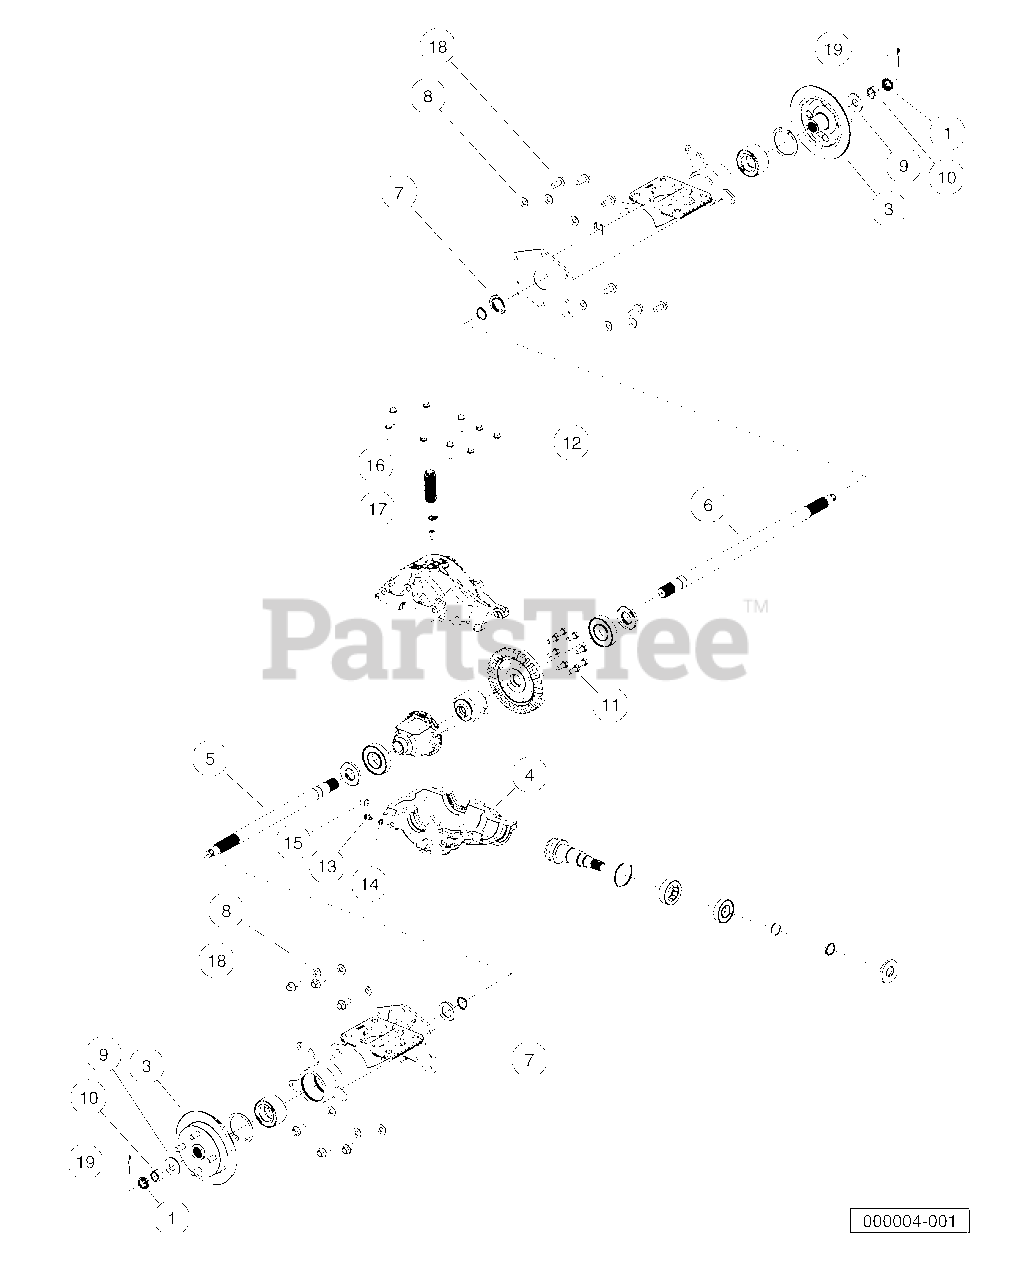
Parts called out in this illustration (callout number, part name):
1	Axle, Rear, Guard Mounts
2	Locking Cap, Nut
3	Assy, Rotor, Brake, Rear
4	Gearcase, Lower, Machined
5	Axle, Right-hand
6	Axle, Left-Hand
7	Washer,counterbored 51 X 30
8	Washer, Bellevle, 1.063 X .043
9	Washer, Belleville, 49 X 4
10	Nut, Hex, M20 X 1.5 , Modified
11	Screw, M10 X 25
12	Screw,hex Flange, M8 X 35
13	Plug,3/8-16, Hex Flange
14	Washer, .625 X .382 X .60
15	Plug, Square Skt, 1/12-14, Ptf
16	Bellows, Vent, Upper Housing
17	Clamp, Hose, Dw-9.5
18	Screw, Hex Fl, M12 X 1.75 X 30
19	Pin, Cotter, 5/32 X 1.25
